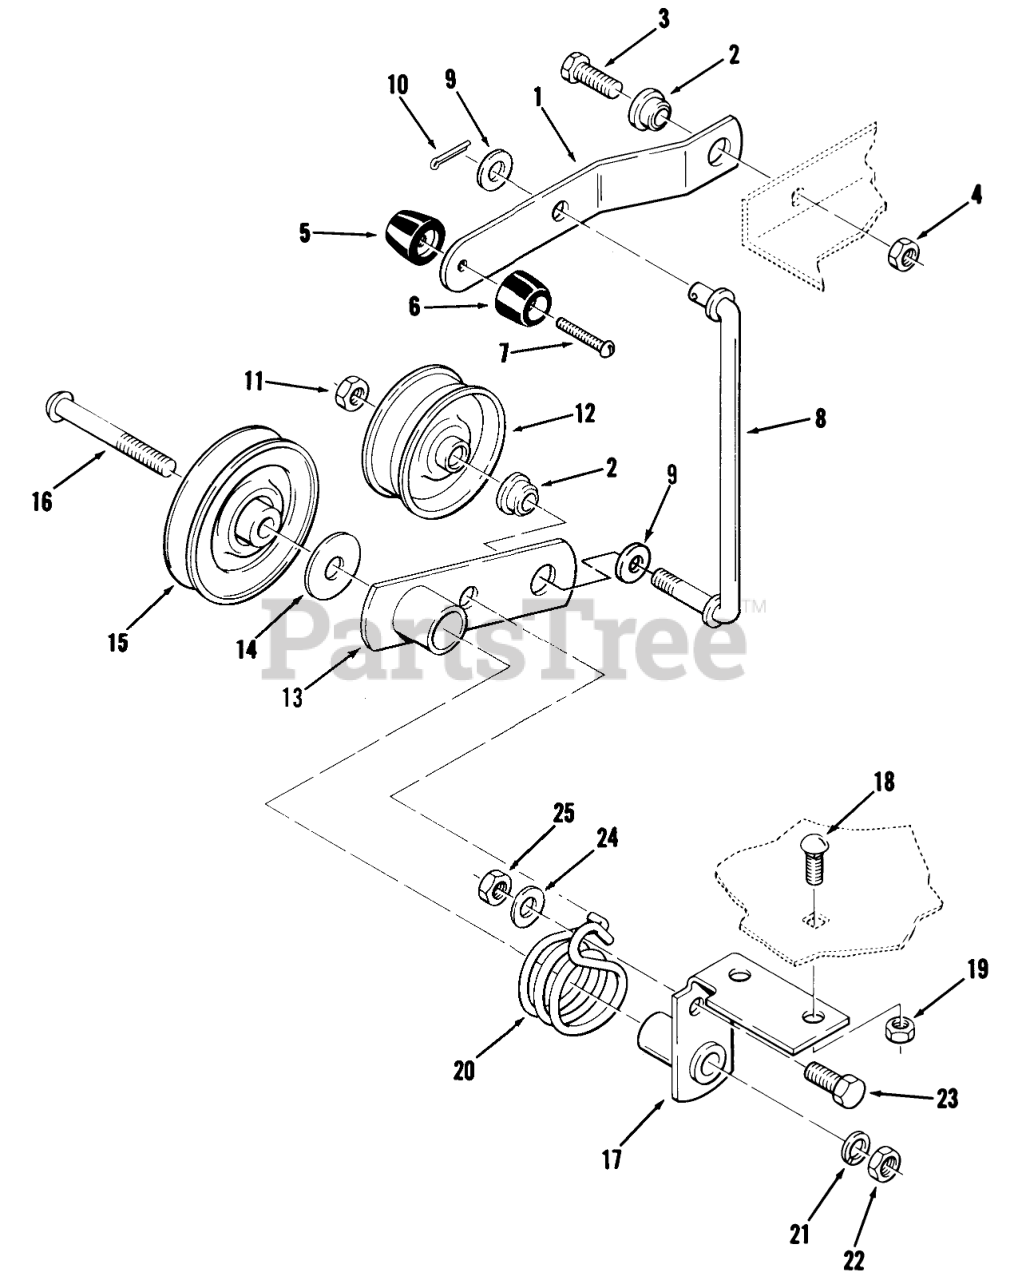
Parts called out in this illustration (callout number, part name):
1	BEARING CAM ROLLER
2	ASSY ROD END
8	KNOB
13	BEARING-CAM RETURN
21	TRUNNION-LIFT
24	WASHER 5/16 SAE
32	CLIP - SPRING
34	SPACER
35	SPACER
37	GRIP
38	SPRING-EXTENSION
43	Special Washer
